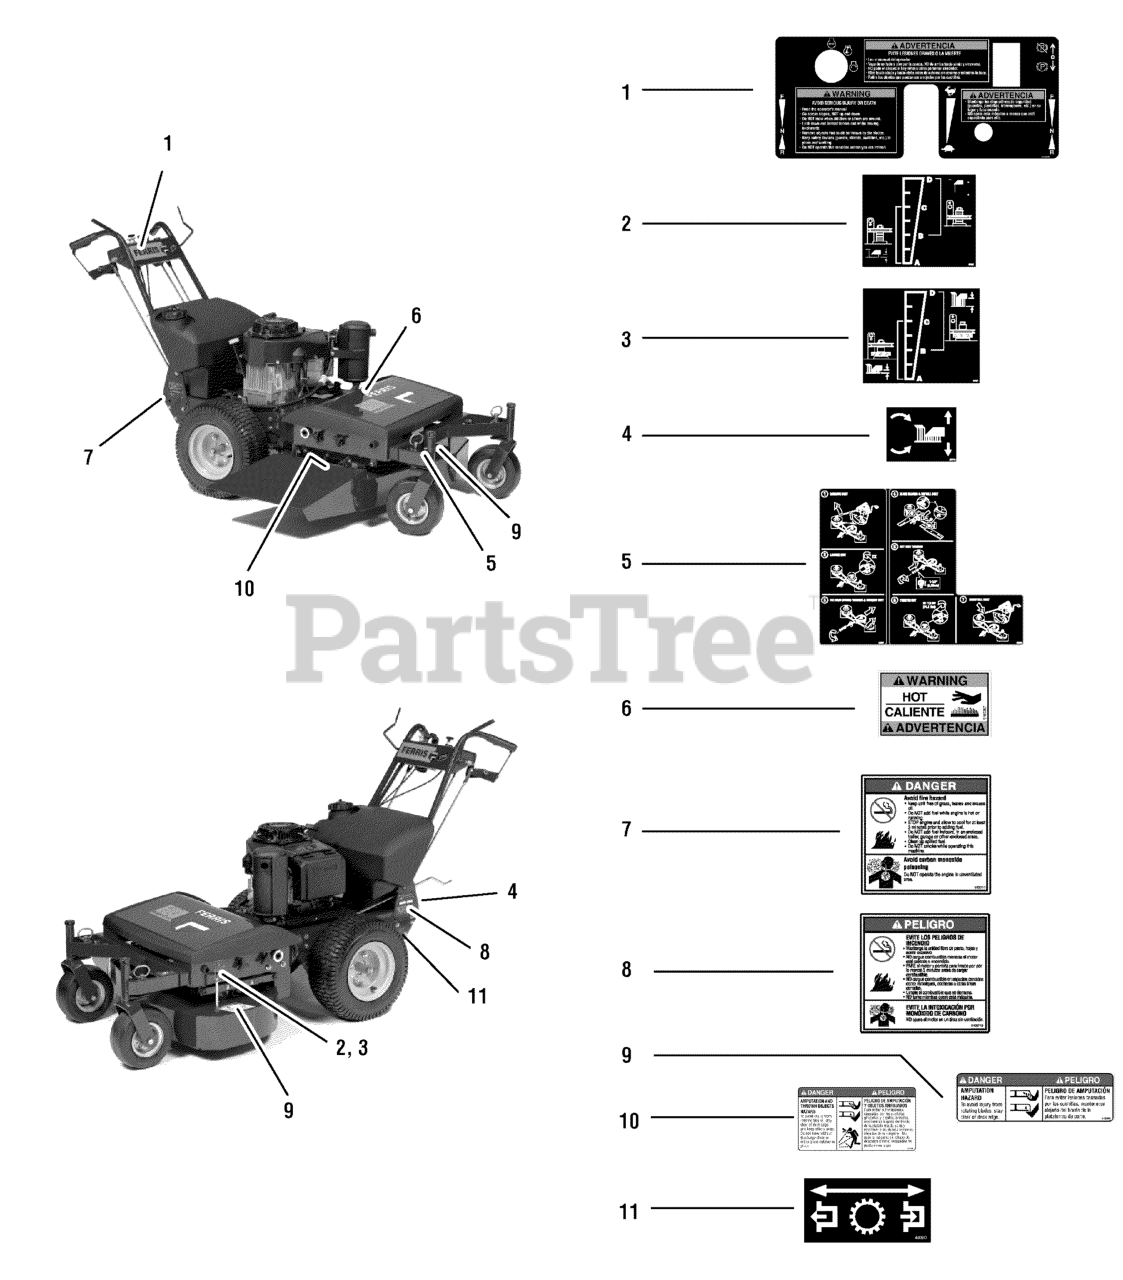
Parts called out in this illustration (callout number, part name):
1	DECAL, CONTROL PLANEL, HC
2	DECAL, HEIGHT OF CUT
3	DECAL, HEIGHT OF CUT
4	DECAL, DECK HEIGHT ADJUST
5	DECAL, BELT R&R
6	DECAL, WARNING, HOT
7	DECAL, DANGER
8	DECAL, DANGER, FIRE (SP)
9	DECAL, DANGER, MOWER
10	DECAL, DANGER, MOWER DISCHARGE
11	DECAL, HYDRO RELEASE
